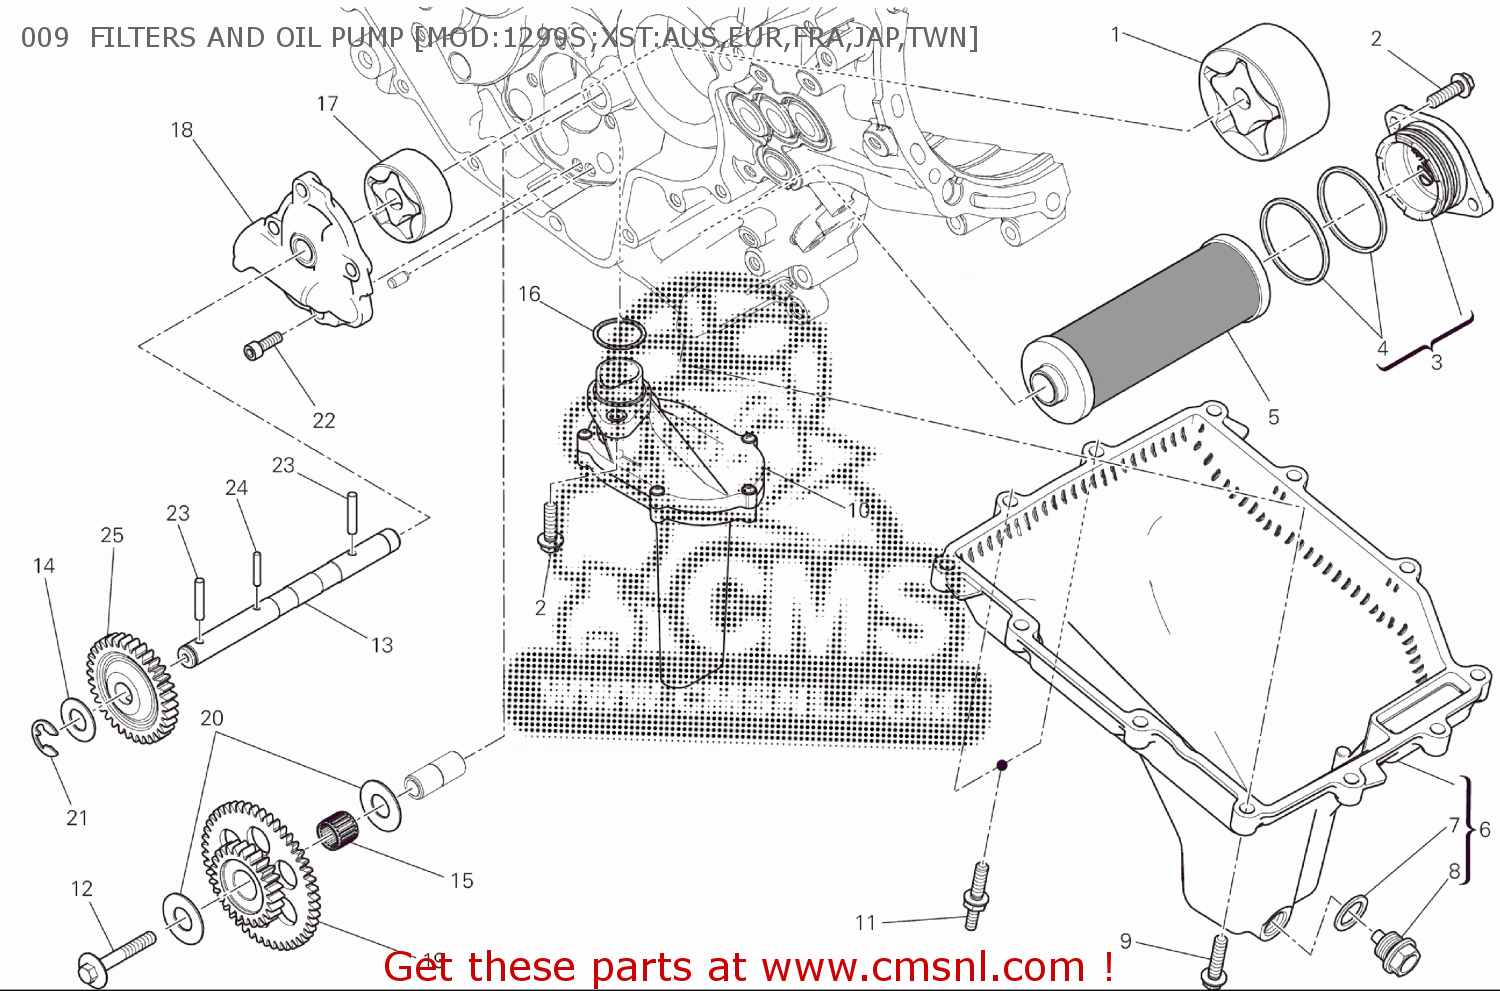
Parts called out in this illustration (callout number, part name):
1	OIL PUMP RETURN
2	SCREW
3	FILTER COVER UNIT
4	O-RING
5	FILTER, OIL
6	OIL PAN
7	WASHER
8	OIL DRAIN PLUG WITH MAGNET
9	SCREW
10	MESH FILTER ASSEMBLY
11	SCREW, SPECIAL
12	SCREW, SPECIAL
13	OIL PUMP DRIVE SHAFT
14	WASHER, THRUST
15	BEARING, NEEDLE
16	O-RING
17	OIL PUMP DELIVERY
18	OIL PUMP COVER
19	GEAR, PUMP DRIVEN
20	WASHER, THRUST
21	SNAP RING
22	SCREW TCEI M6X16
23	ROLLER
24	ROLLER
25	IDLE GEAR
